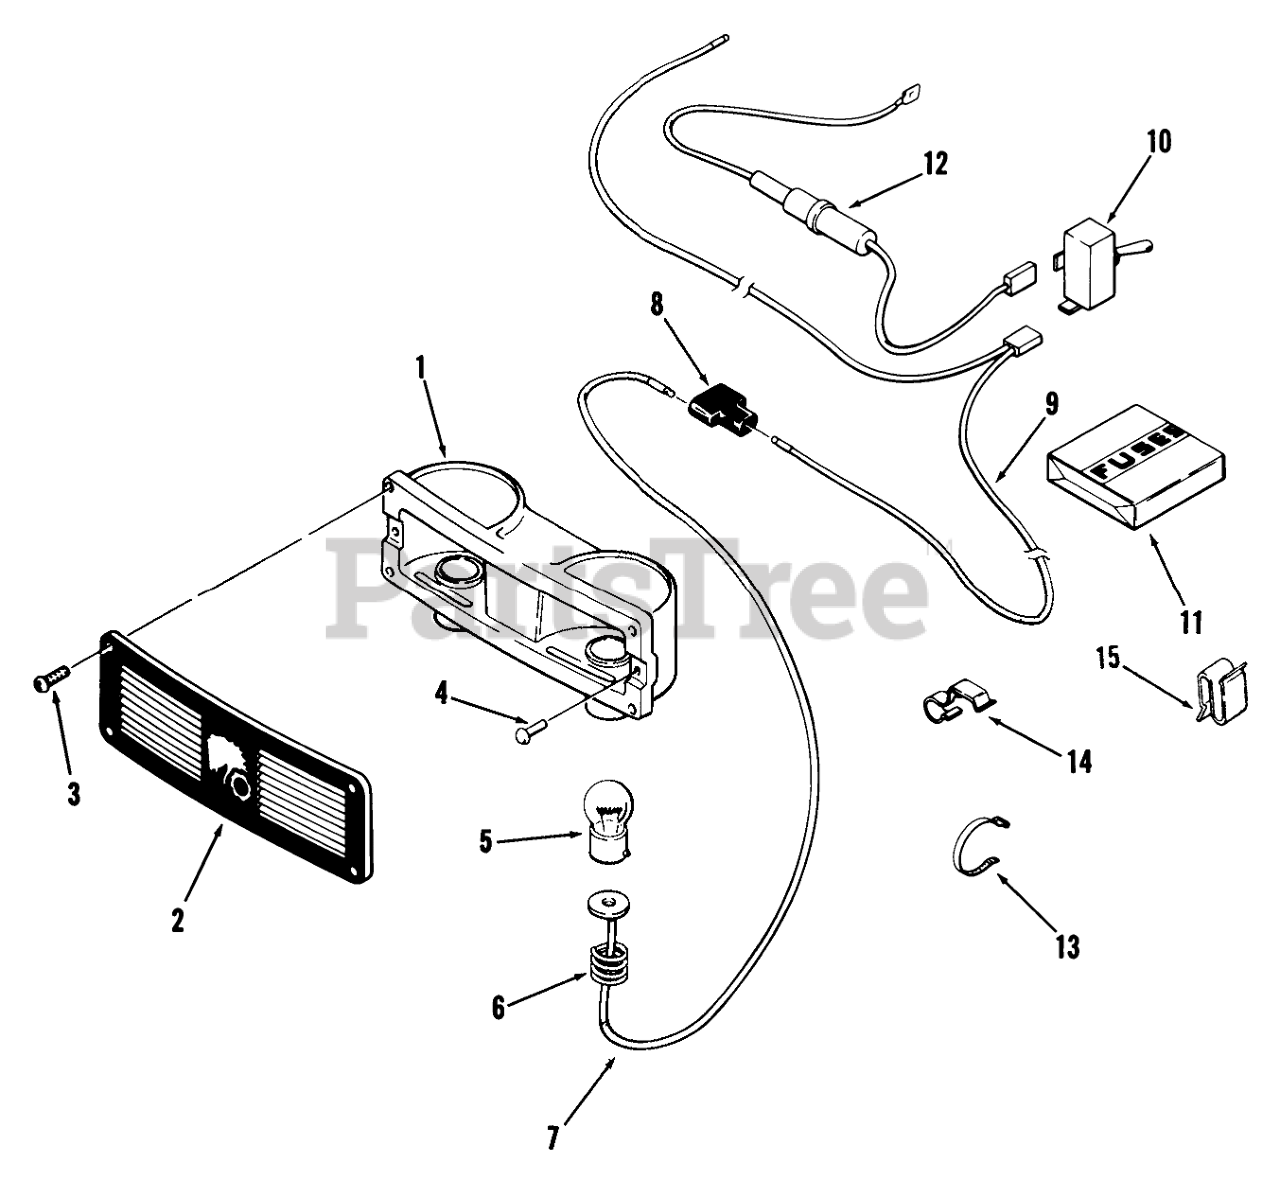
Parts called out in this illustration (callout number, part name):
1	ASSY REFLECTOR HOUSI
2	Lens
3	Pan HD Swage
4	RIVET
5	BULB
6	SPRING
7	WIRE ASSY
8	CONNECTOR 3 WIRE
9	HARNESS-WIRING
10	SWITCH-LIGHTS
12	ASSY FUSED CONNECTOR
13	PLASTIC TIE
14	CLIP-WIRE
15	SPEED CLIP
